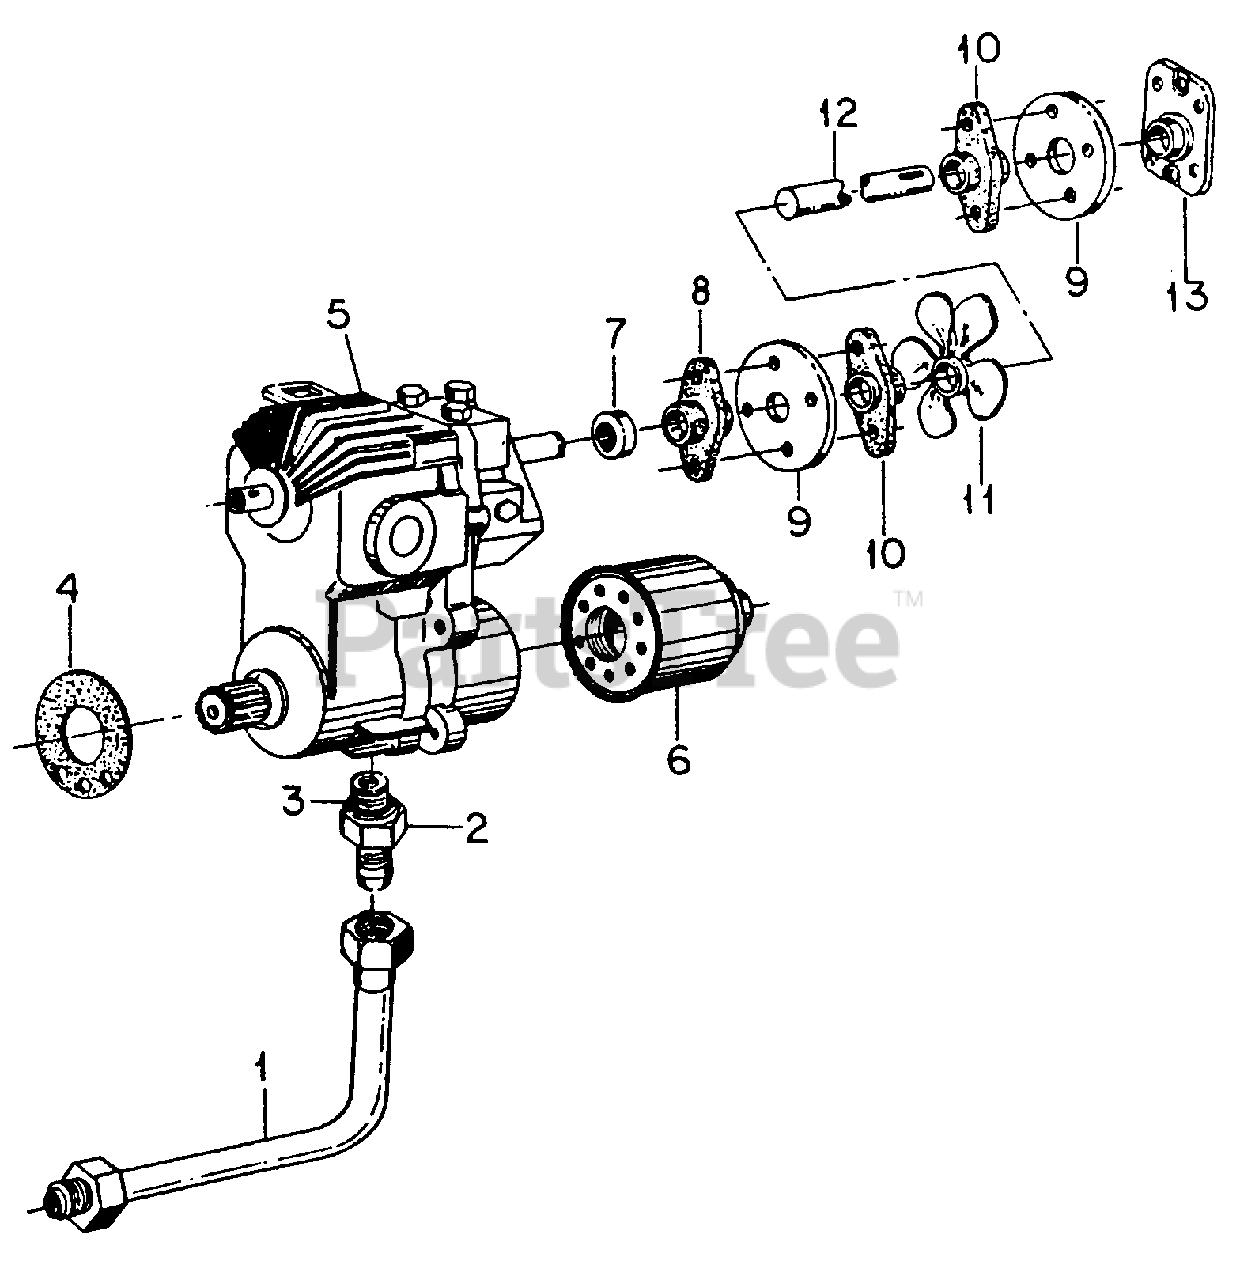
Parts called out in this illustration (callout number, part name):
1	Tube Assy, Transmission
2	Connector, 5/8 C-Z Hyd Fld Short Swivel
3	O-Ring, 5/8 OD Tube Class 6
4	Gasket, Front
5	Transmission, Hydrostatic
6	Filter, Oil
7	Bushing, Self Aligning Ball
8	Coupler, Drive Shaft
9	Disc, Flexible
10	Arm, Coupling
11	Fan, Cooling
12	Shaft, Drive
13	Flange, Drive Shaft
